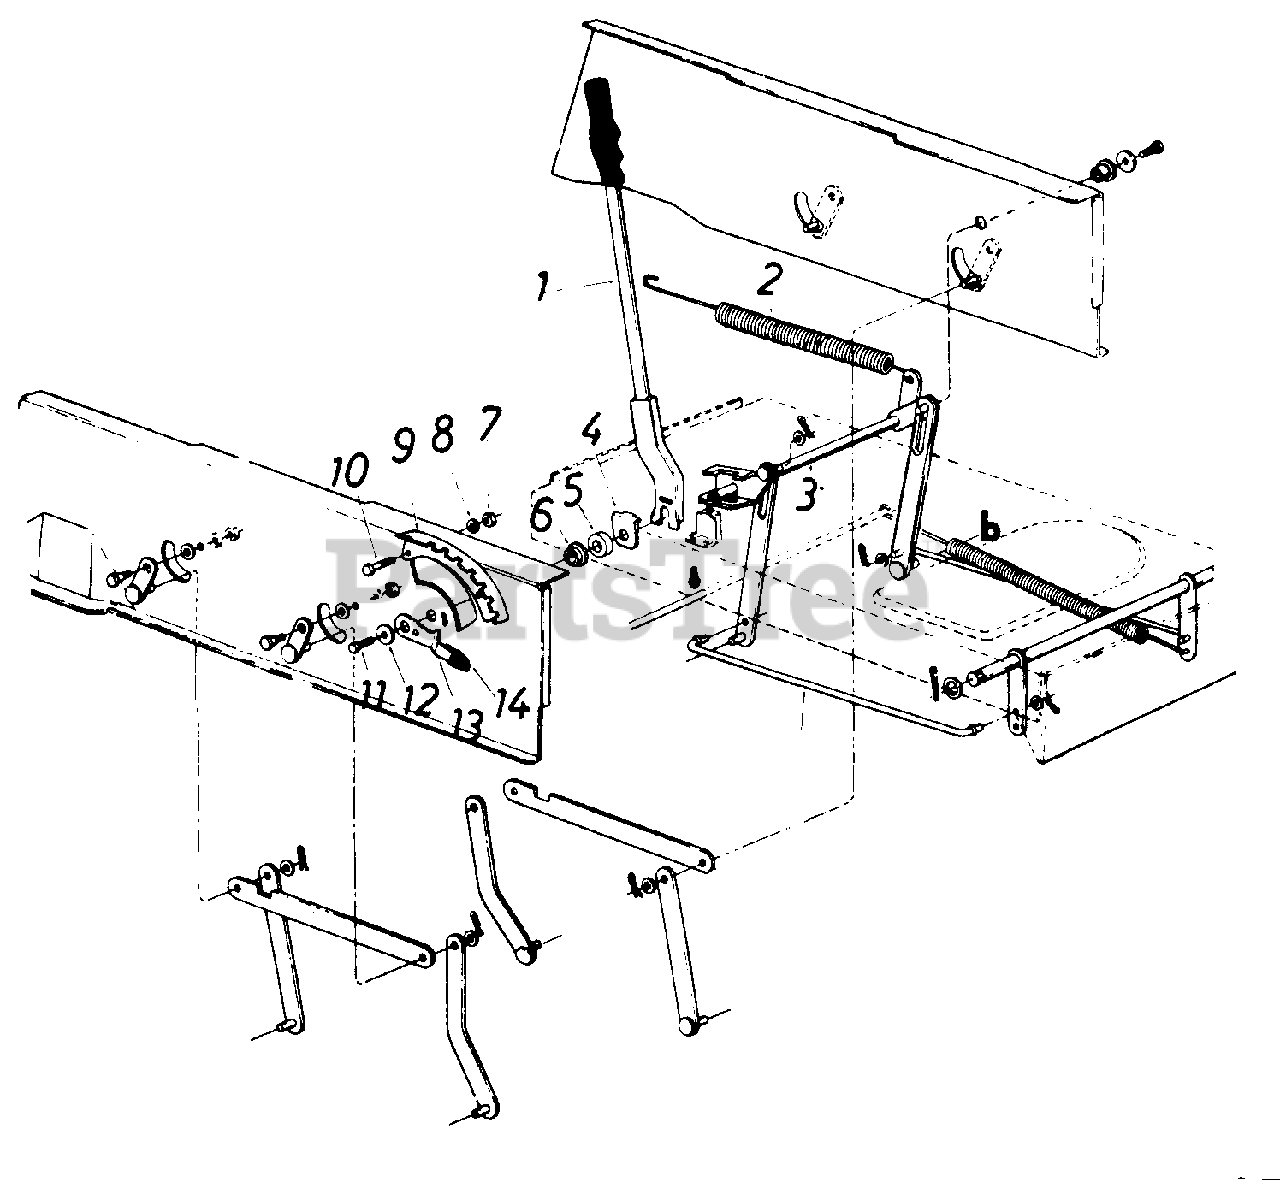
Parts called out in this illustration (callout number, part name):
1	Lift Handle Ass'y.
2	Extension Spring .99" O.D. x 11" Lg.
5	Rubber Wash. 1.50" O.D. x .63" I.D.
6	Flange Wash. .628" I.D. x 1.25" 0. D.
7	Hex Nut 5/16-18 Thd.
8	L.-Wash. 5/16" I.D.
9	Index Bracket
10	Hex Bolt 5/16-18 x .75" Lg.
11	Hex Wash. Hd. Self-Tap Scr. 5/16-18 x .62" Lg.
12	Fl.-Wash. .344" I.C. x 1.25" Lg.
13	Deck Lift-Down Stop
14	Knob
